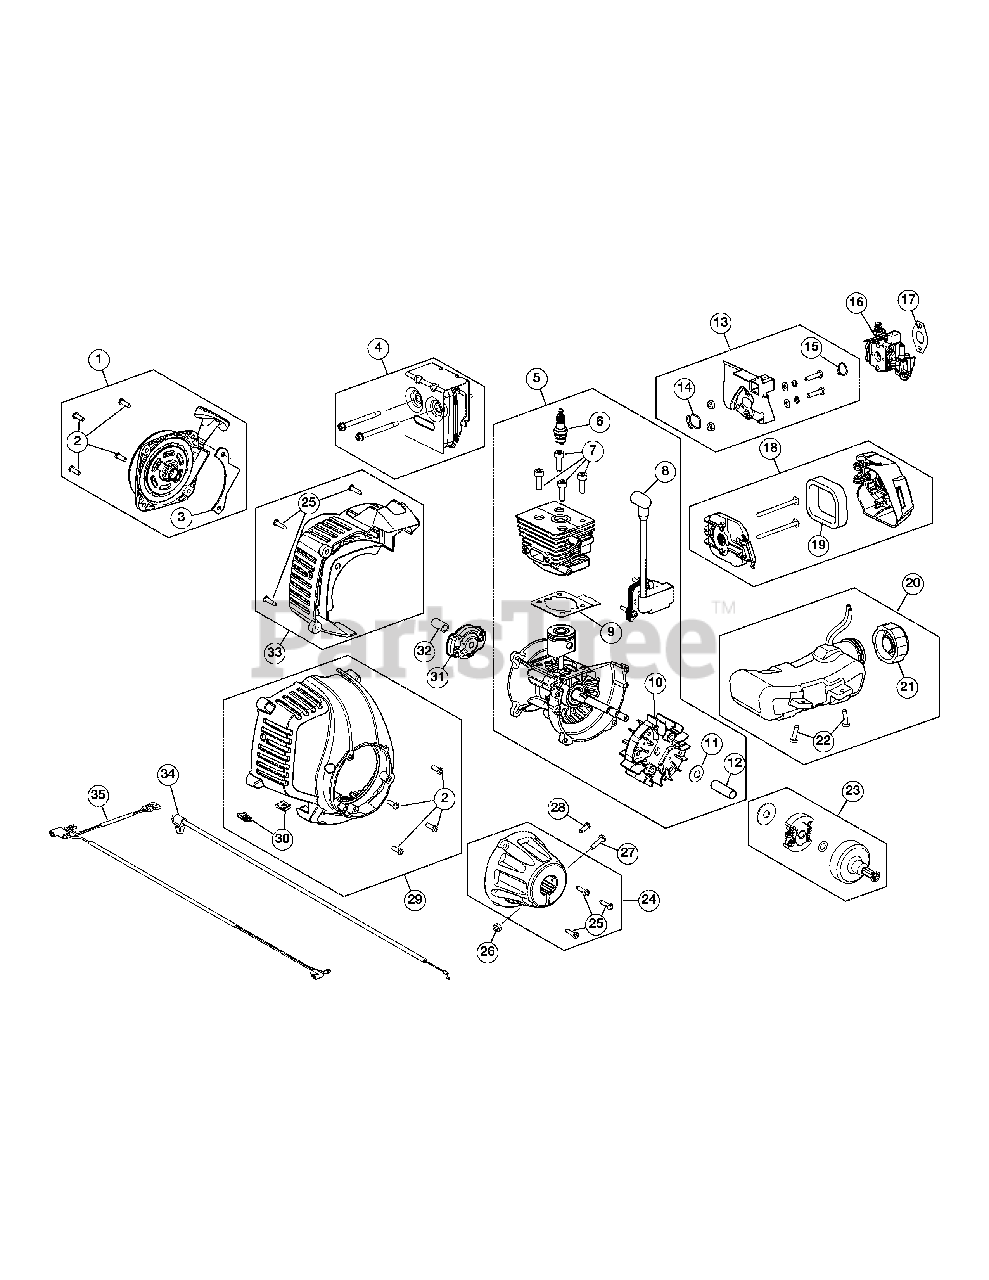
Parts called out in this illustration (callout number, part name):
1	Rear Cover Assembly (Incl. 2 & 3)
2	Starter Screw
3	Starter Assembly Guard (Incl. 2)
4	Muffler Assembly
5	Short Block Assembly
6	Spark Plug
7	Cylinder Bolt
8	Module Assembly
9	Cylinder Gasket
10	Flywheel Assembly
11	Washer
12	Spacer
13	Insulator Assembly (Incl. 14 & 15)
14	Insulator O-Ring
15	Carburetor O-Ring
16	Carburetor
17	Carburetor Gasket
18	Air Cleaner Assembly (Incl. 19)
19	Air Cleaner Filter
20	Fuel Tank Assembly (Incl. 21 & 22)
21	Fuel Tank Cap
22	Fuel Tank Screw
23	Clutch Assembly
24	Clutch Cover Assembly (Incl. 25)
25	Cover Screw
26	Clamp Nut
27	Clamp Screw
28	Anti-Rotation Screw
29	Front Engine Cover Assembly (Incl. 2 & 30)
30	U-Shaped Nut
31	Pawl Assembly
32	Adapter
33	Rear Engine Cover Assembly (Incl. 25)
34	Throttle Cable
35	Lead Wires
